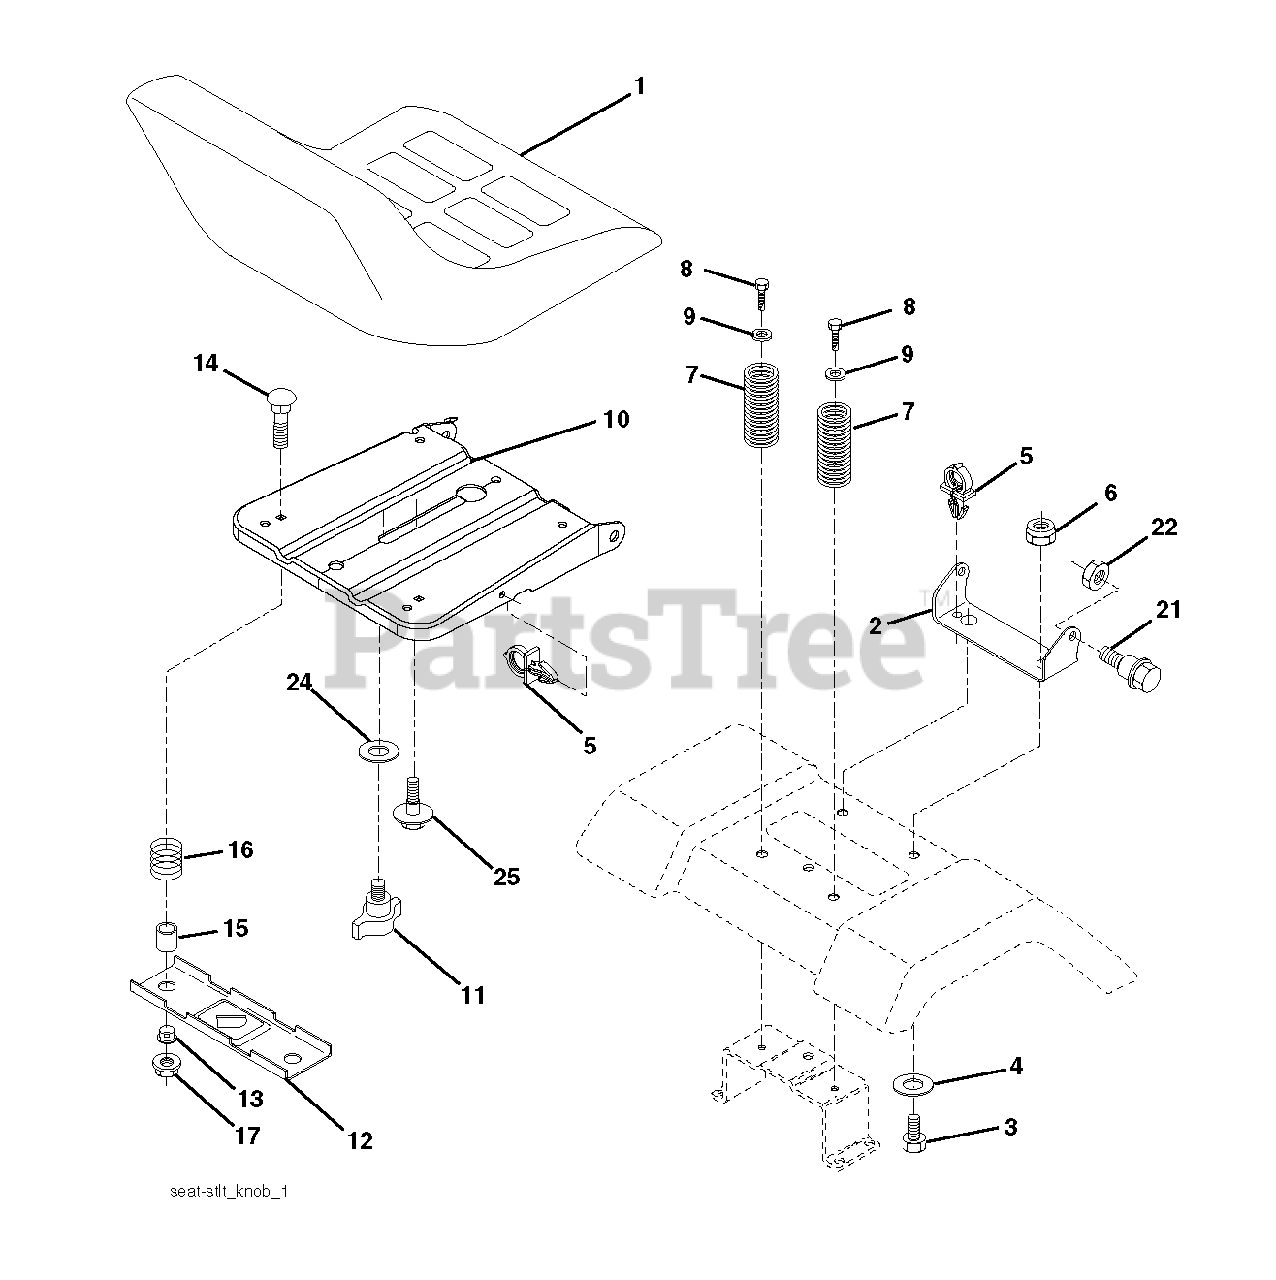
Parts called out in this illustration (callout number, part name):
1	SEAT.XG090.BLK.KB/BLT.NO-LOG
2	SEAT PIVOT BRKT
3	BOLT, HEX 3/8-16X1
4	WASHER PM
5	PUSH CLIP
6	NUT
7	SPRING COMPRESSION
8	SCREW 3/8-16X1
10	PAN.ASM.SEAT.1SLOT
11	KNOB.SEAT.ADJ.WINGNUT
12	BRKT.MNTNG.SWITCH.SEAT.BLACK
14	BOLT.ROUND.HEAD.SQUARE.NECK
15	SPACER SPLIT 28X.96
17	NUT T
21	BOLT.SHOULDER.5/16-18
22	NUT.71038.31-18.HEX.NYLOCK
25	BOLT,SHOULD
